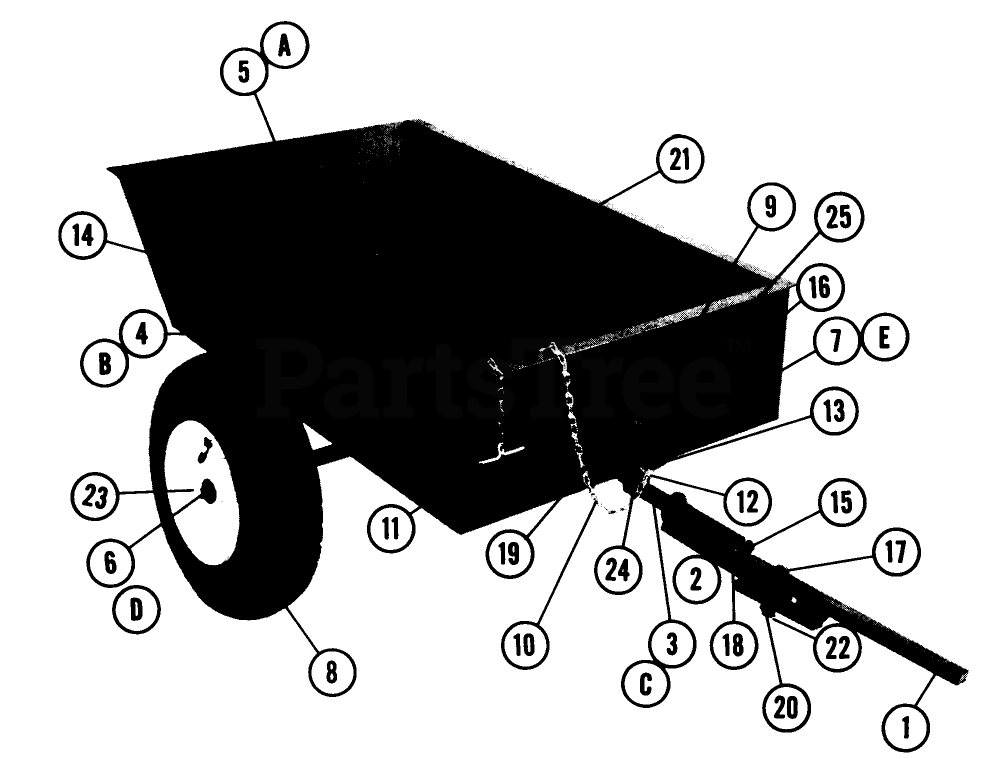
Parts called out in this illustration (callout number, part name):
1	Swivel Hitch
2	Hitch Bar
3	Tongue
4	Frame
5	Bed
6	Axle
7	Latch Front
9	Spring Torsion
10	Chain, Dumping 36"
11	Handle, Trip
12	Clevis Link
13	Stove Bolt, 3/16 x 5/8
14	Hex Head Cap
15	Hex Head Cap Screw
16	HHCS, 3/8-16 x 2
17	HHCS, 1/2-20 x 2-1/2
18	Hex Nut
19	31300 '65-67&UP 20
20	Bearing Cup
21	Lockwasher
22	Cotter Key
23	Cotter Pin
24	Lock Washer
25	Hex Head Cap
